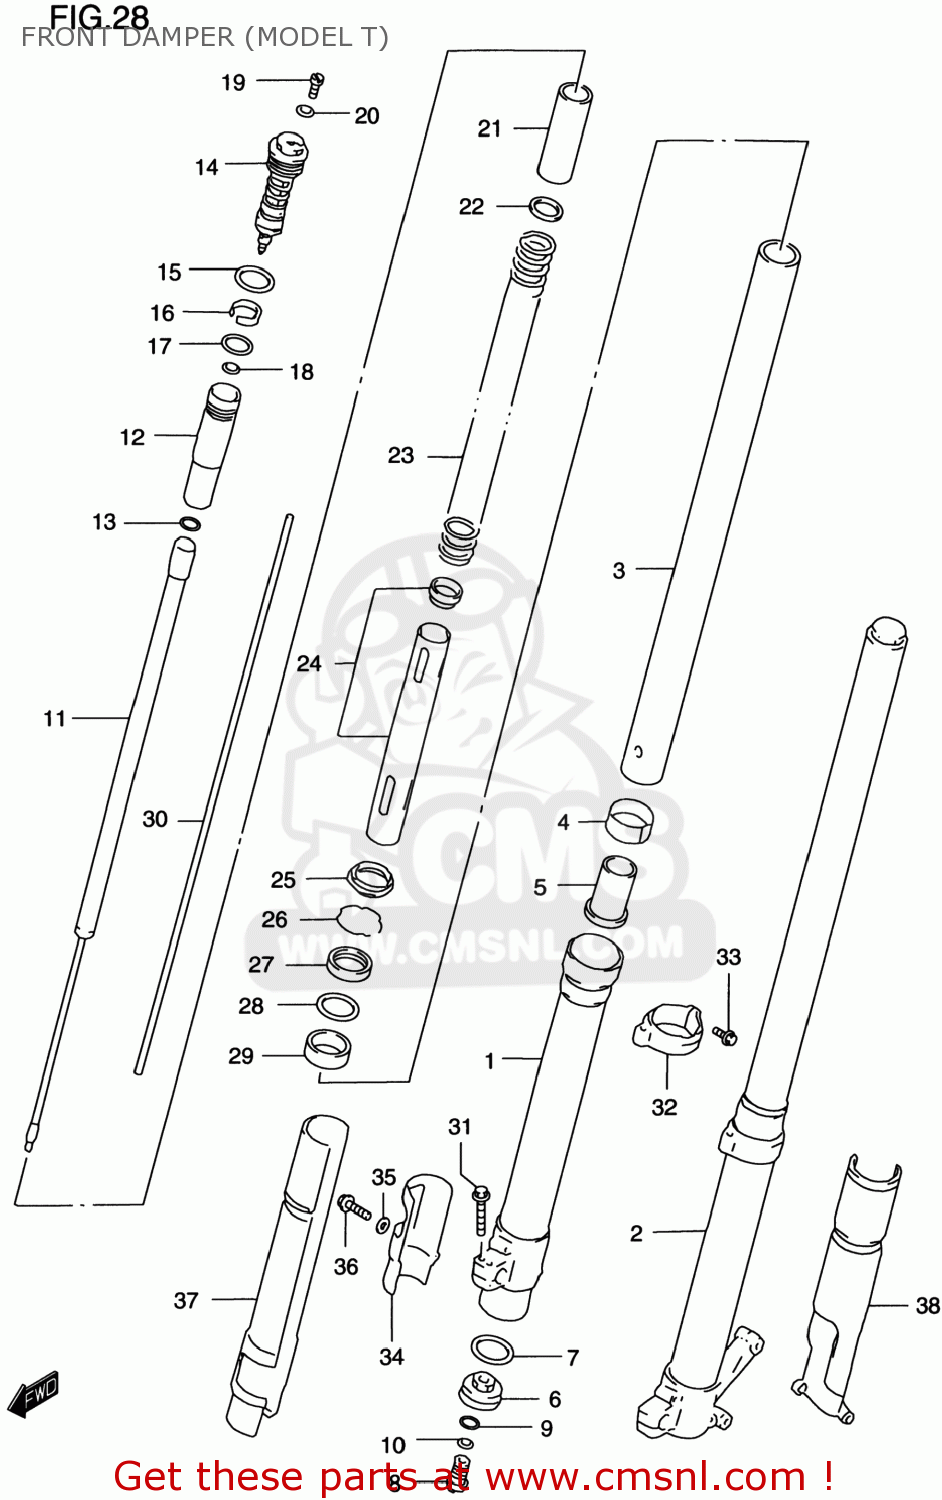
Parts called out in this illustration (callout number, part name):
1	TUBE,OUTER,R
2	TUBE,OUTER,LEFT
3	TUBE,INNER
4	BUSH,SLIDE
5	PIECE,OIL LOCK
6	PLATE,END
7	O RING
8	BOLT,CTR
9	GASKET (NAS)
10	O RING,CTR BOLT
11	DAMPER
12	TANK,SUB
13	O RING,CTR BOLT UPR
14	BOLT,FORK
15	O RING
16	BUSH,FORK BOLT SLIDE
17	O-RING,FORK BOLT,CENTER
18	O-RING,FORK BOLT,LOWER
19	BOLT,PLUG
20	O RING,PLUG
21	COLLAR,SPRING
22	JOINT,SPRING
23	SPRING,FR(K=0.42)
24	COLLAR,SPRING
25	SEAL,DUST
26	RING,STOPPER
27	SEAL,OIL
28	SPACER,SEAL
29	BUSH,GUIDE
30	ROD,PUSH
31	BOLT,HANDLE HOLDER(8X35)
32	GUIDE,FR PROTECTOR,R
33	BOLT,PROTECTOR GUIDE,6
34	PROTECTOR,OUTER TUBE,R
35	WASHER
36	BOLT
37	PROTECTOR,OUTER TUBE,R
38	PROTECTOR,OUTER TUBE,L
